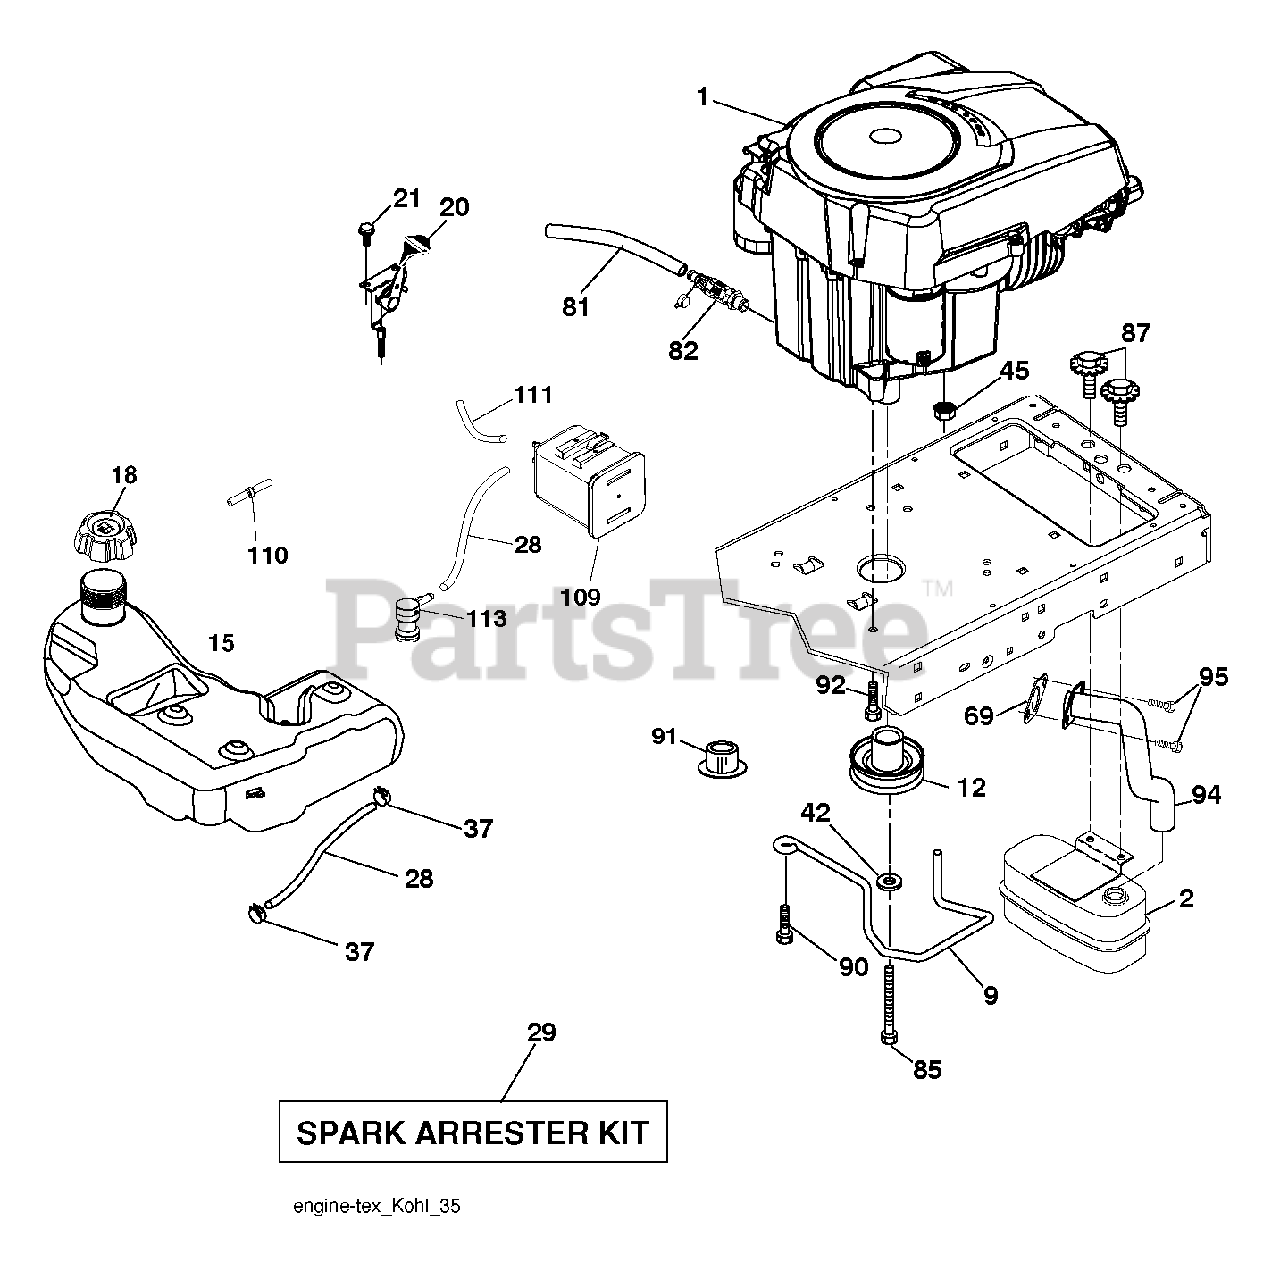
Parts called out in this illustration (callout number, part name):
2	MUFFLER.SINGLE.CYL.KOHL/B&S
9	KEEPER.BELT.ENGINE.4.2
12	PULLEY ENGINE
15	TANK.ASM.FUEL.3GA.CARB
18	CAP.ASM.FL.RITCH.3"E10.SYM.498
20	CONTROL.TH/CK.COBRA.KO
21	SCREW.#10 X 0.750.BOS
28	LINE.FUEL.64"REAR.EMIS
29	KIT.SPARK ARRESTOR 794945 B&S
37	HOSE CLAMP
42	LOCKWASHER
45	NUT
69	GASKET.EXHAUST.KOHLER
81	TUBE, DRAIN OIL ASM.
82	VALUE.OIL.DRAIN
85	BOLT HEX 7/16-20X4-1/4"
87	Bolt, 5/16-18 X 1-3/4
90	SCREW 3/8-16X1
91	BUSHING.1.375OD
92	SCREW 3/8-16X1
94	RP.TUBE.EXHAUST.KOHL.COURAGE
95	SCREW.SOCKET HD.5/16-1
109	CANNISTER, CARBON
110	VALVE.ASM.ANTI-SLOSH
111	RP PURGE LINE
113	VALVE.SLANT.CARTRDG.90 DEG.TEX
